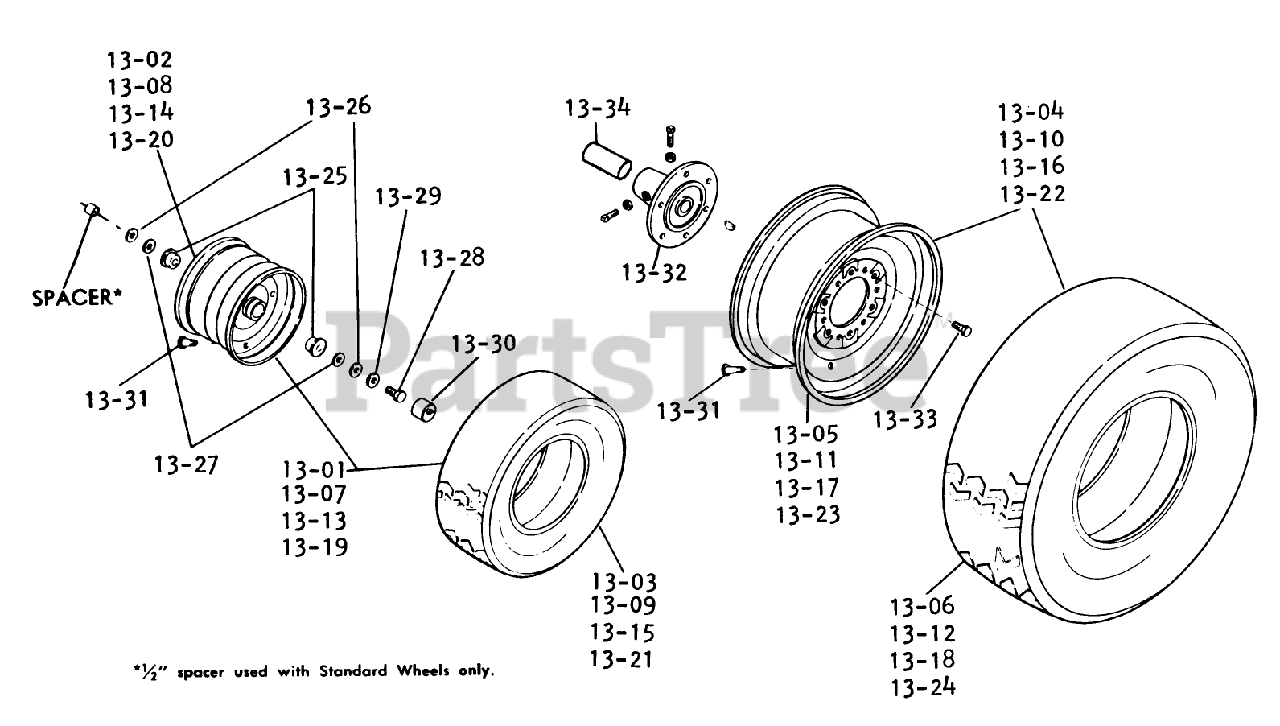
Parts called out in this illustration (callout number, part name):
13-01	ASSY-WHEEL
13-07	ASSY-WHEEL
13-13	ASSY-WHEEL
13-16	ORDER 110006 OR 110007
13-18	Rear Tire 27 x 8.50-15 Cleat
13-19	ASSY-WHEEL
13-22	Rear Wheel Tire Cleat
13-26	WASHER
13-29	WASHER
13-31	VALVE
13-33	BOLT-LUG, WHEEL
